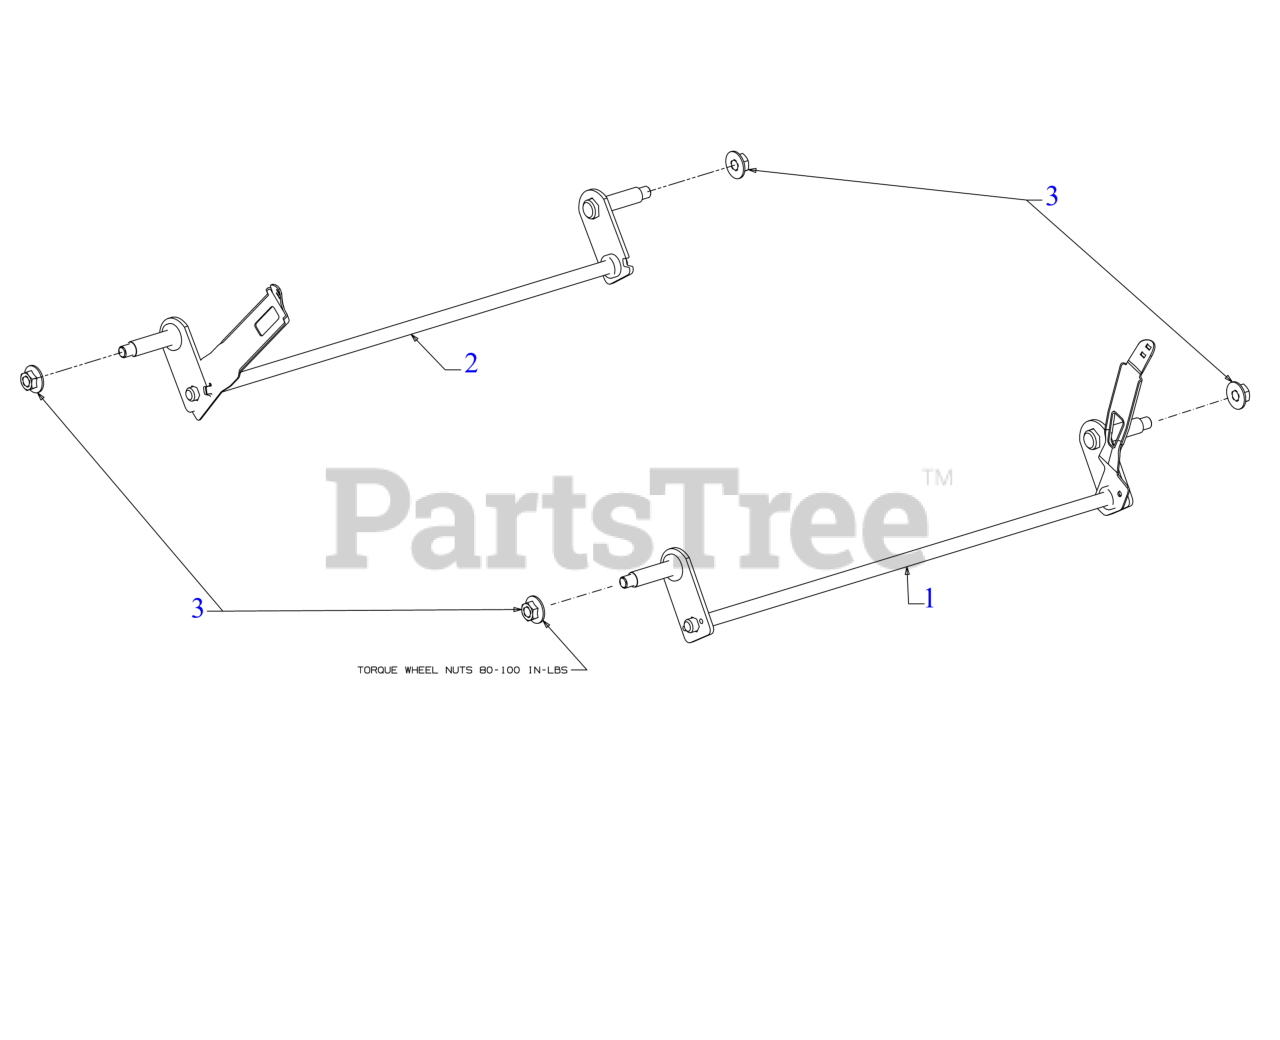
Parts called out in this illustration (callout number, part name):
1	FRONT AXLE ASSEMBLY
2	8" REAR AXLE ASSEMBLY
3	FLANGE LOCK NUT
